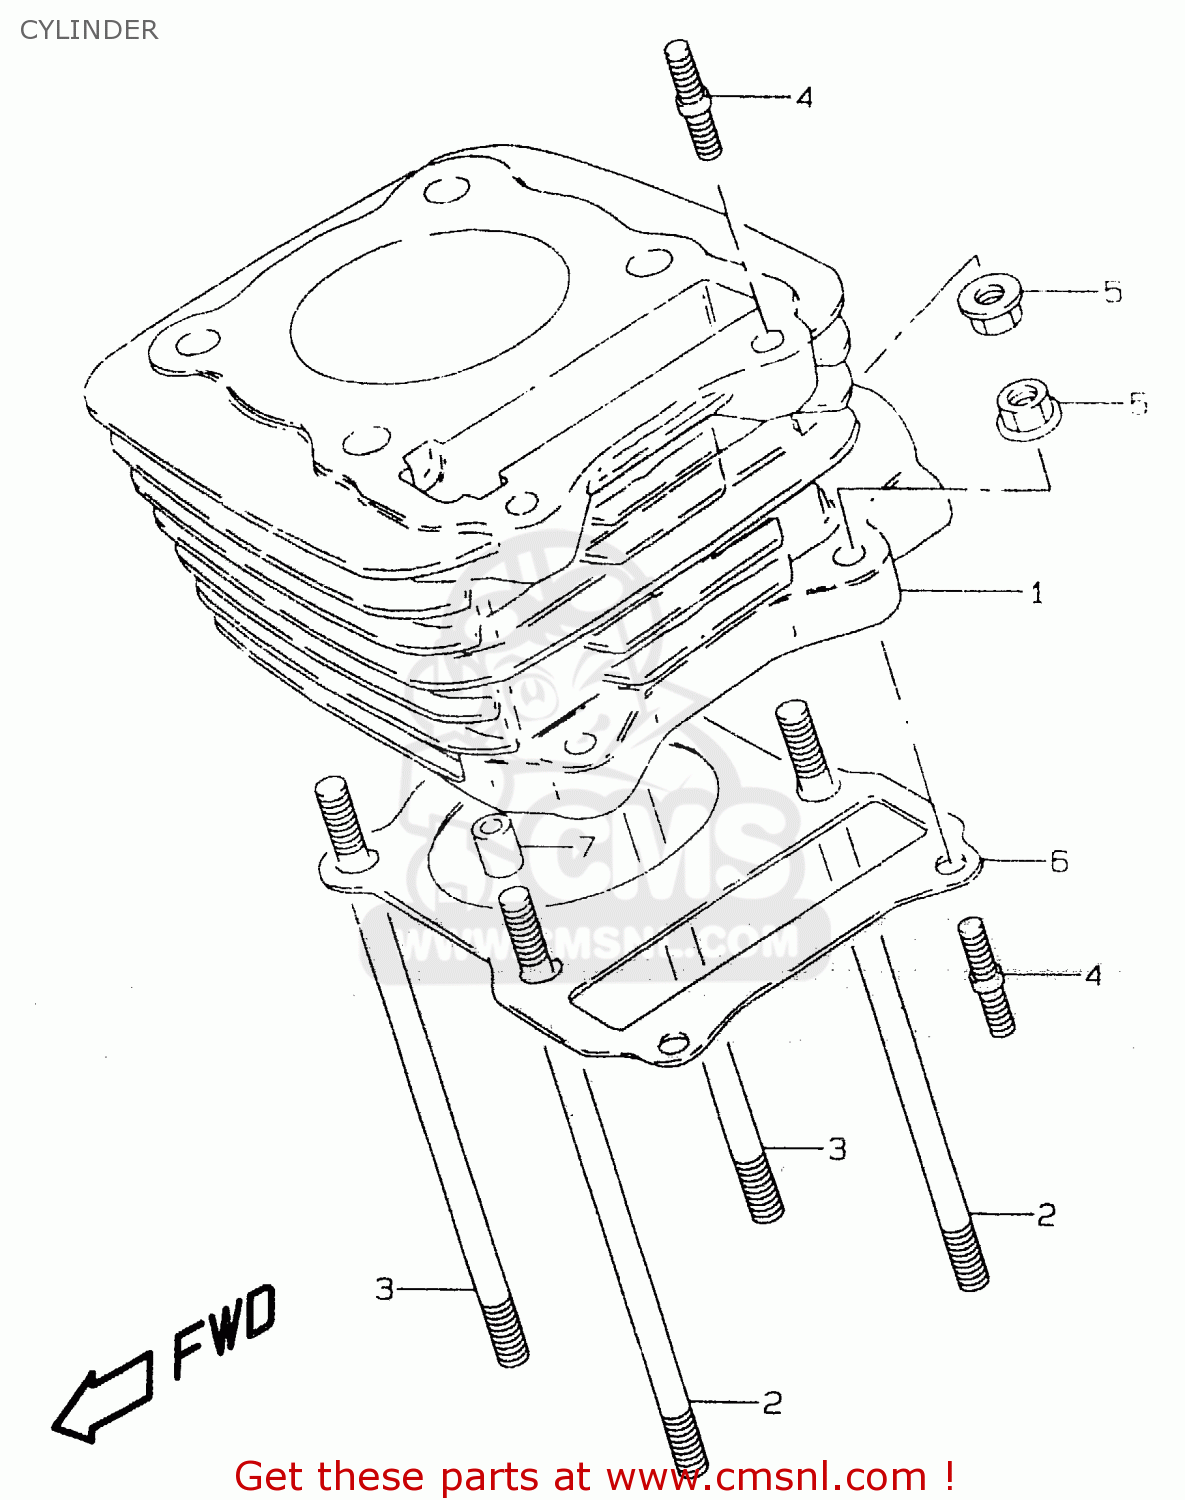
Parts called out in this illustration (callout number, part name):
1	CYLINDER
2	BOLT,STUD
3	BOLT,STUD
4	BOLT,STUD
5	NUT
6	GASKET,CYLINDER (NAS)
7	PIN
